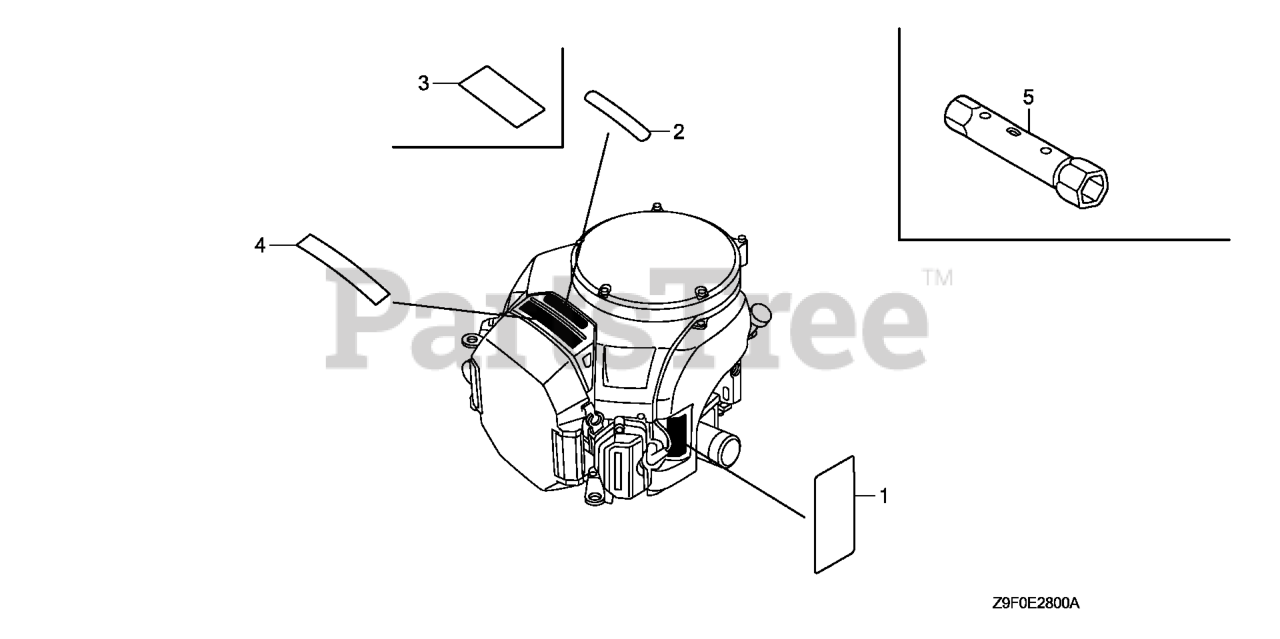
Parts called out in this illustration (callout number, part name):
1	MARK, OPERATOR CAUTION (ENGLISH)(MADE IN JAPAN)
2	EMBLEM (GXV690)
4	MARK, HONDA
